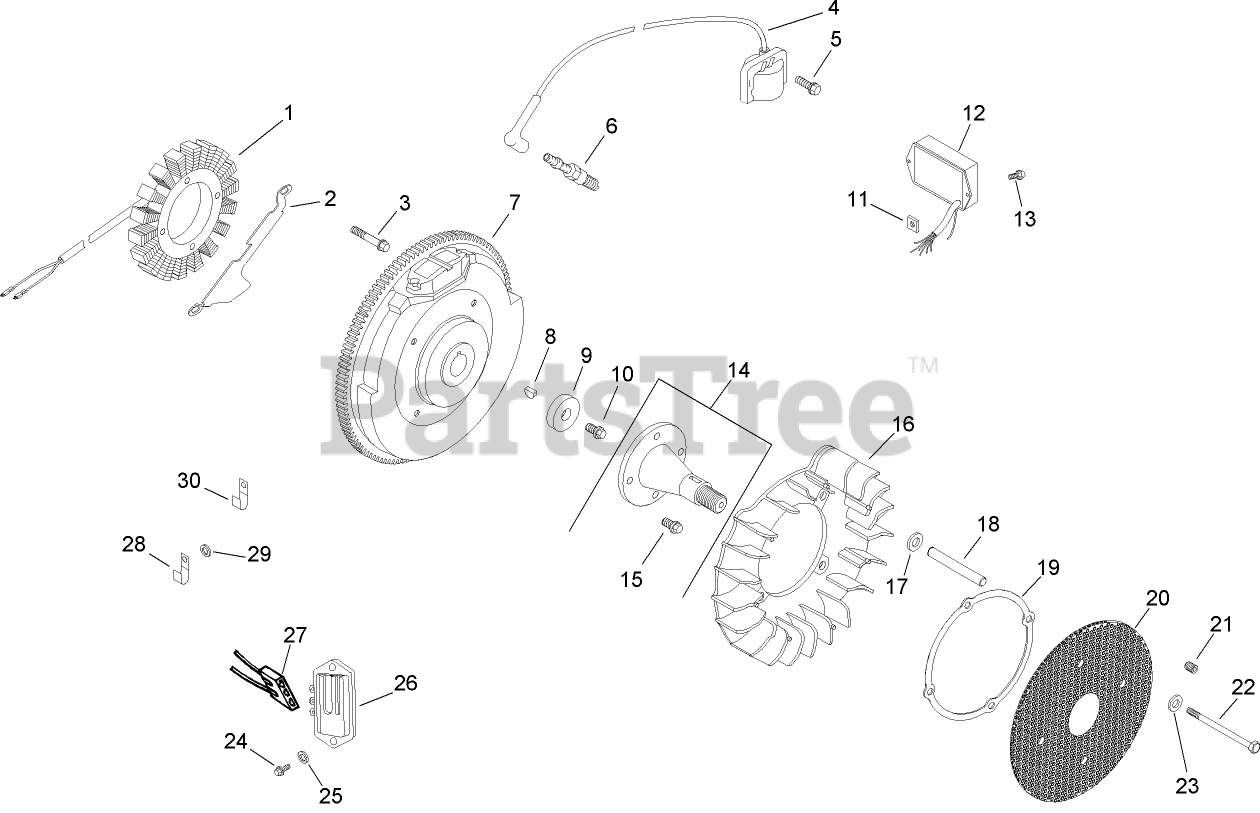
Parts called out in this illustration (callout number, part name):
1	Stator Kit
2	Bracket-Strap, Ground
3	SCREW-THREAD FORMING (M5X0.8X25)
4	Module-Advance, Spark
5	SCREW-FLANGE, THREAD FORMING (M5X.8X20)
6	SPARK PLUG
7	Flywheel
8	KEY (3/16 X 5/8)
9	WASHER-FLAT (13/32)
10	SCREW-FLANGE (M10X1.5X45)
11	NUT-PLASTIC
12	Module-Ignition
13	SCREW-PPH (11-16X1/2)
14	Front Drive Shaft Kit
15	Screw-HF (M8x1.25x25)
16	Fan
17	Washer-Spring (10MM)
18	Spacer
19	Ring-Support
20	Screen-Grass
21	Screw-Set (10-24X.25)
22	Screw-HH (M6x1.0x100)
23	WASHER-FLAT (1/4)
24	SCREW-PHL HD (11-16X.88)
25	WASHER-FLAT (.188)
26	Rectifier-Regulator
27	Connector (3 contact)
28	CLIP-CABLE
29	WASHER-FLAT (1/4)
30	Clip-Cable
